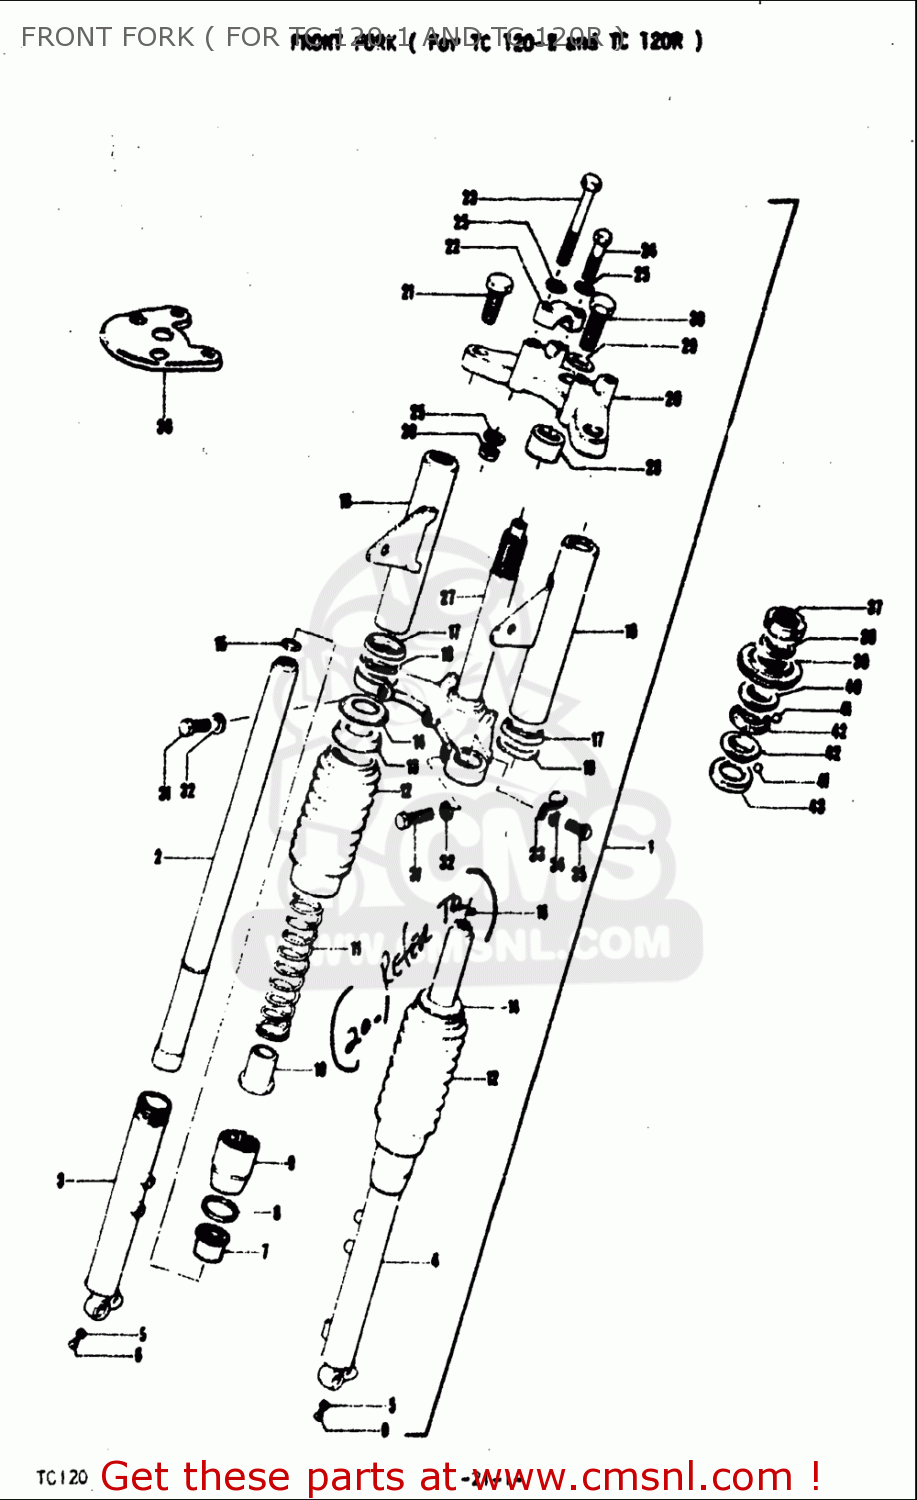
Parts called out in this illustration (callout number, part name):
5	GASKET,DRAIN,PLUG (NAS)
6	OIL DRAIN PLUG
8	O RING,OIL SEAL LWR
10	DUST SEAL,FRONT FORK
15	O RING
17	SEAT,HEADLAMP BRACKET
21	BOLT,FR FORK(10X33)
22	HOLDER,HANDLEBAR
23	BOLT,HANDLEBAR CLAMP
25	WASHER,LOCK
26	NUT
30	BOLT,FR FORK(10X33)
31	BOLT
32	WASHER,LOCK
33	CLIP,BRAKE CABLE
34	WASHER,LOCK
38	WASHER
39	NUT,STEERING STEM
41	BALL
